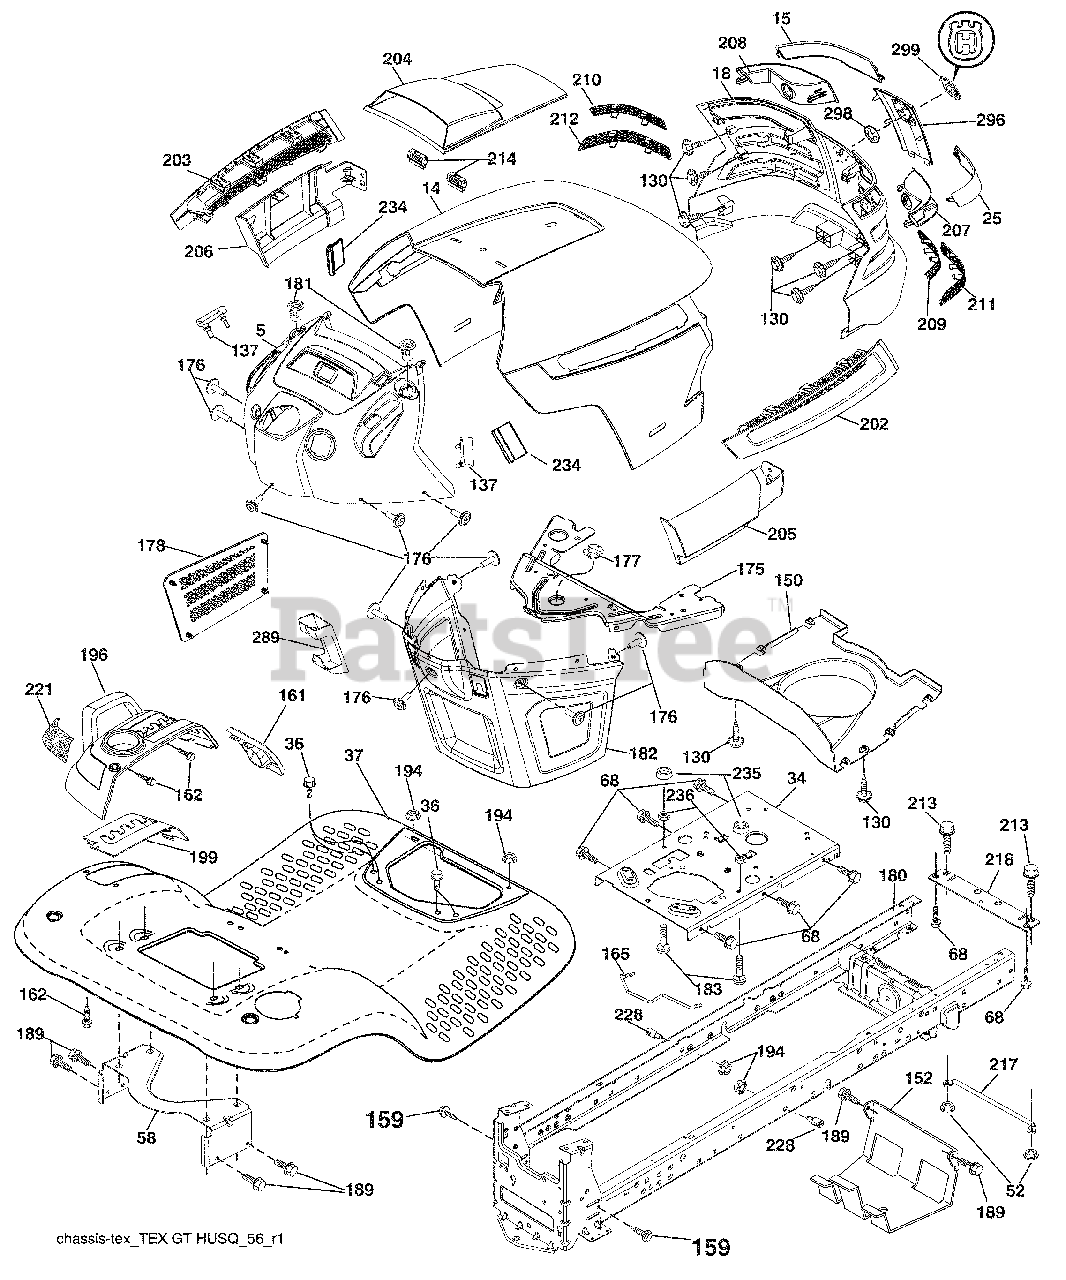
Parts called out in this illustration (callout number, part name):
14	Hood
34	Plate Engine
36	Screw 5/16-18 x 3/4
37	Fender
52	Nut Crown Lock 5/16-18
58	Bracket Fender
68	Screw 5/16-18 x 1/2
130	Screw #10 x 0.750 BOS Thread
137	Bumper Dash
150	Duct Heat Hood
152	Shield Browning/Debris\
159	Screw 3/8-16 x 3/4
161	Console Fuel Window
162	Screw Hex Wsh Hi-Lo 1/4 x 1/2
165	Bracket Support Tank
175	Crossmember
176	Screw 10-24 x 5/8 Wshd Qdrx
177	Bushing Steering
178	Cargo Asm. Net
180	Chassis
181	Bushing MMT Fender
182	Dash Lower
183	Bolt 5/16-18 unc x 1-1/4
189	Screw 5/16-18 x 3/4
194	Nut Lock 5/16-18
196	Console Asm. Deck Lift
199	Plate Deck Lift
202	Vent Side Hood RH
203	Vent Side Hood LH
204	Vent Asm Hood Top
205	Skirt Hood Side RH
206	Skirt Hood Side LH
209	Insert Hex Top RH
210	Insert Hex Top LH
211	Insert Hex Bottom RH
212	Insert Hex Bottom LH
213	Bolt Hex Hd 5/16-18 unc x 3/4
214	Clip Retainer
218	Hood Stop X Piece
221	Reflector LH
228	Stud Fastener
234	Bumper Hood
235	Spacer Fender
236	Nut Center Lock 5/16-18 unc
289	Plug Cruise/Phone
299	Logo
